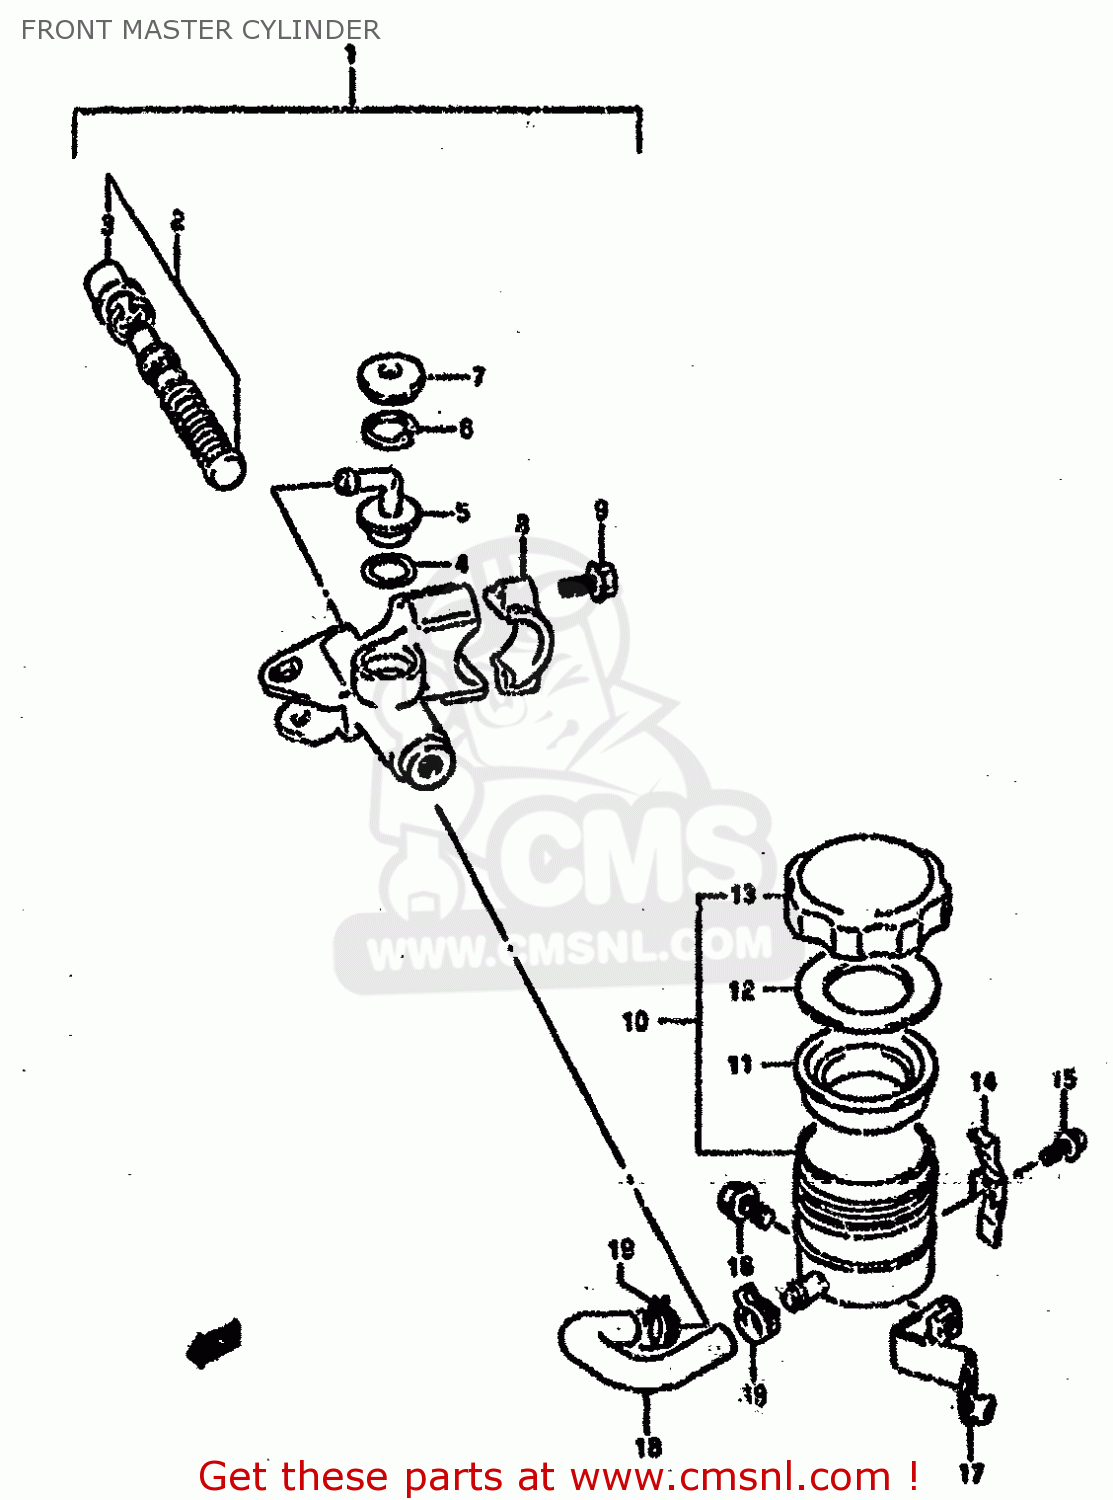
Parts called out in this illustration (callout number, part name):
1	CYLINDER ASSY,FR MASTER
2	PISTON & CUP SET
3	BOOT
4	O RING
5	CONNECTOR
6	CIRCLIP
7	COVER,DUST
8	HOLDER
9	BOLT(6X25)
10	TANK ASSY,RESERVOIR
11	DIAPHRAGM
12	PLATE,DIAPHRAGM
13	CAP
14	PLATE,RESERVOIR TANK CAP
15	SCREW
16	BOLT
17	BRACKET,RESERVOIR TANK
18	HOSE,RESERVOIR TANK FR
19	CLAMP,RESERVOIR TANK FR
